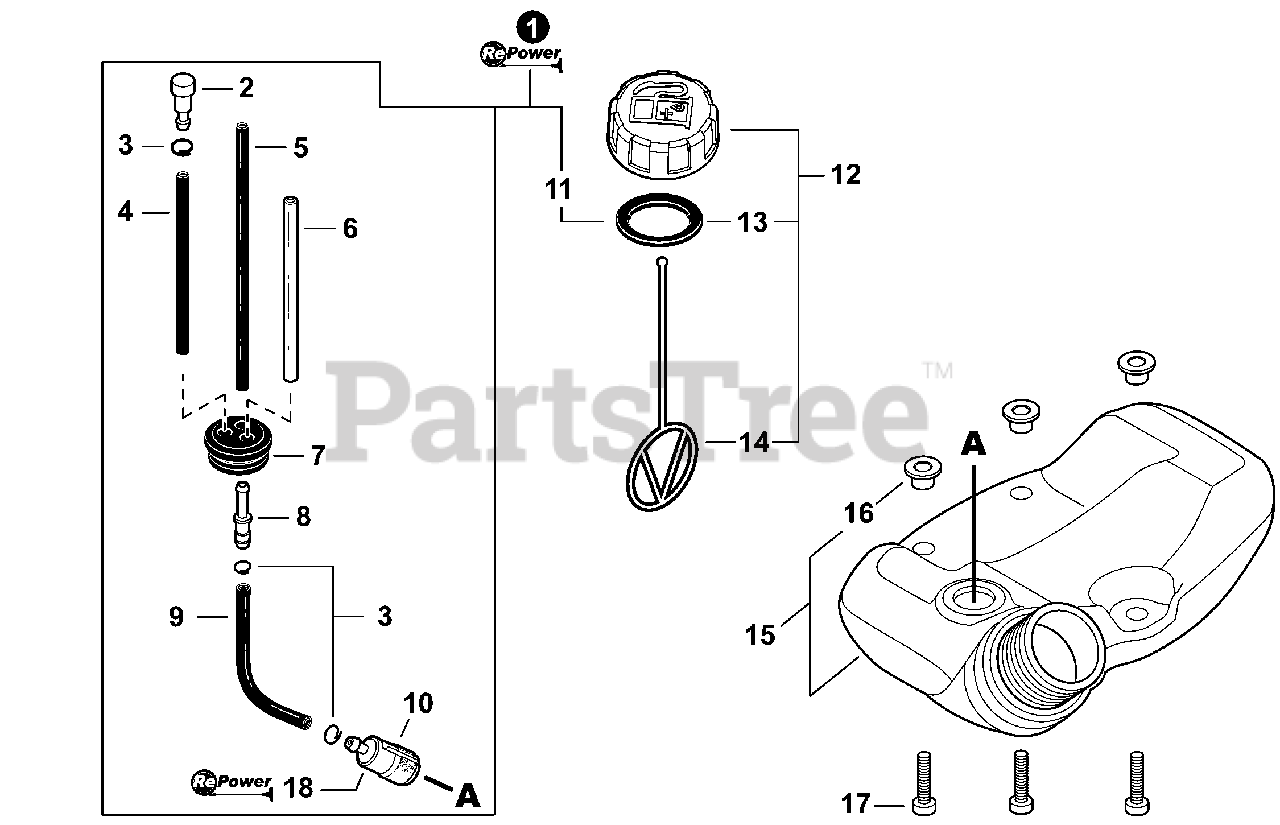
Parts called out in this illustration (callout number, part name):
1	FUEL SYSTEM KIT
2	VENT ASSY
3	CLIP Ø6
4	PIPE, FUEL 3×5×90 BLACK
5	PIPE, FUEL 3×5×74 BLACK
6	PIPE, FUEL 3×6×80 CLEAR
7	GROMMET, FUEL Ø5
8	CONNECTOR, PIPE Ø5ר3.5
9	PIPE, FUEL 3×5×130 BLACK
10	FILTER, FUEL
11	GASKET, FUEL CAP
12	CAP ASSY, FUEL
13	GASKET, FUEL CAP
14	CONNECTOR, CAP L= 123
15	TANK ASSY, FUEL
16	COLLAR 5
17	BOLT, TORX 5×20
18	TUNE-UP KIT - REPOWER
